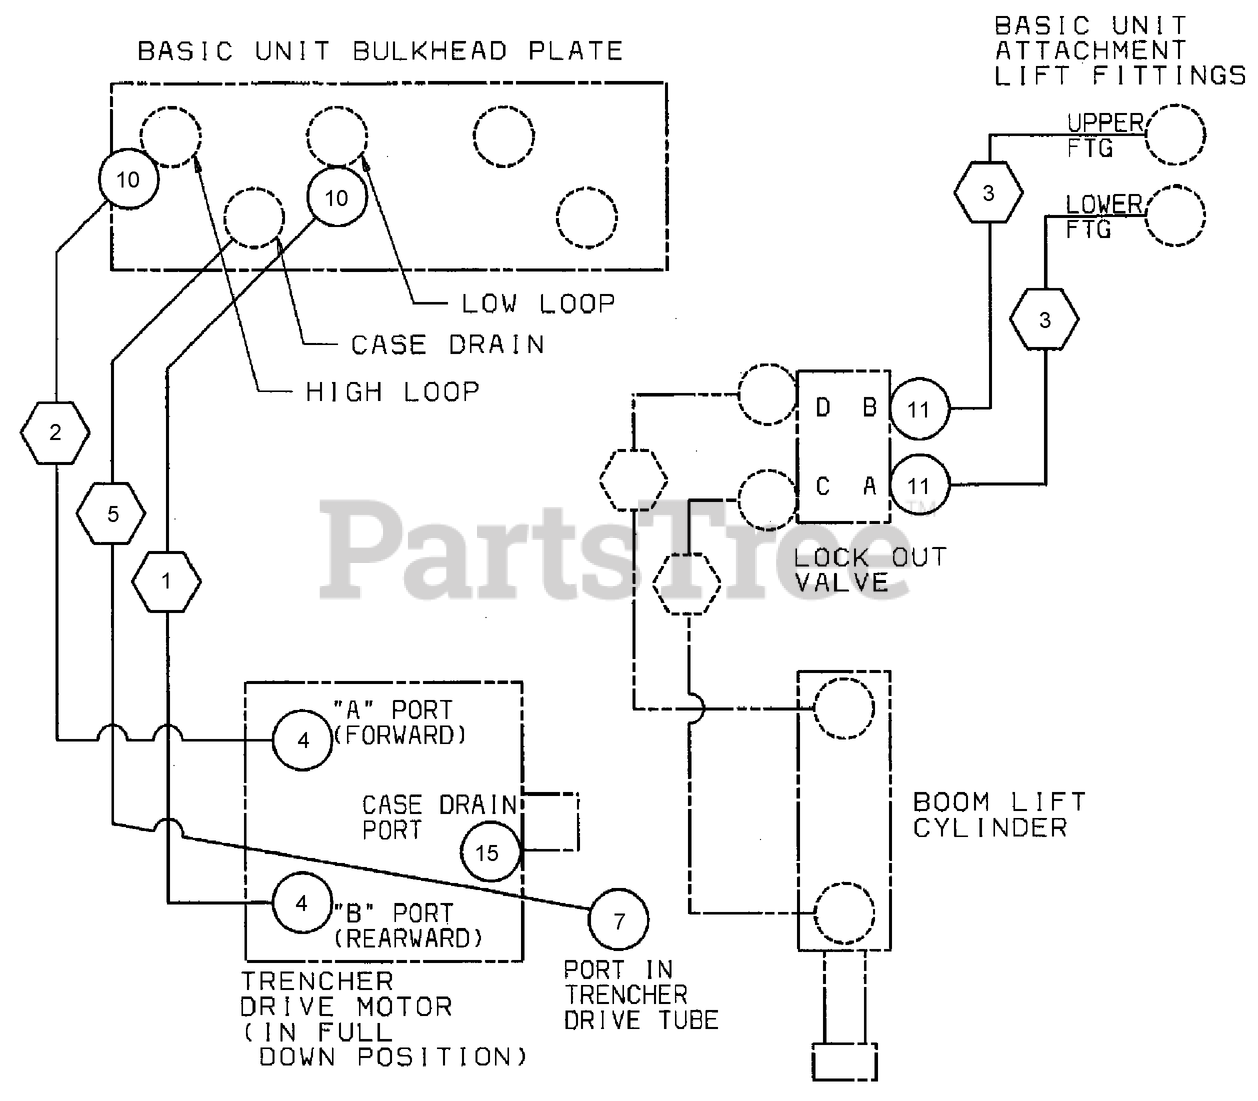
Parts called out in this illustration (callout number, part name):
1	HOSE-Low Pressure Loop
2	HOSE-High Pressure Loop
3	HOSE-Boom Lift
4	FITTING-STRAIGHT
5	HOSE-Case Drain
7	ELBOW-90 Adj 37FL 5/8 Tube
10	REDUCER-16FF-12MF
11	CONNECTOR
15	PLUG-Hex Hd, ORB 3/8
